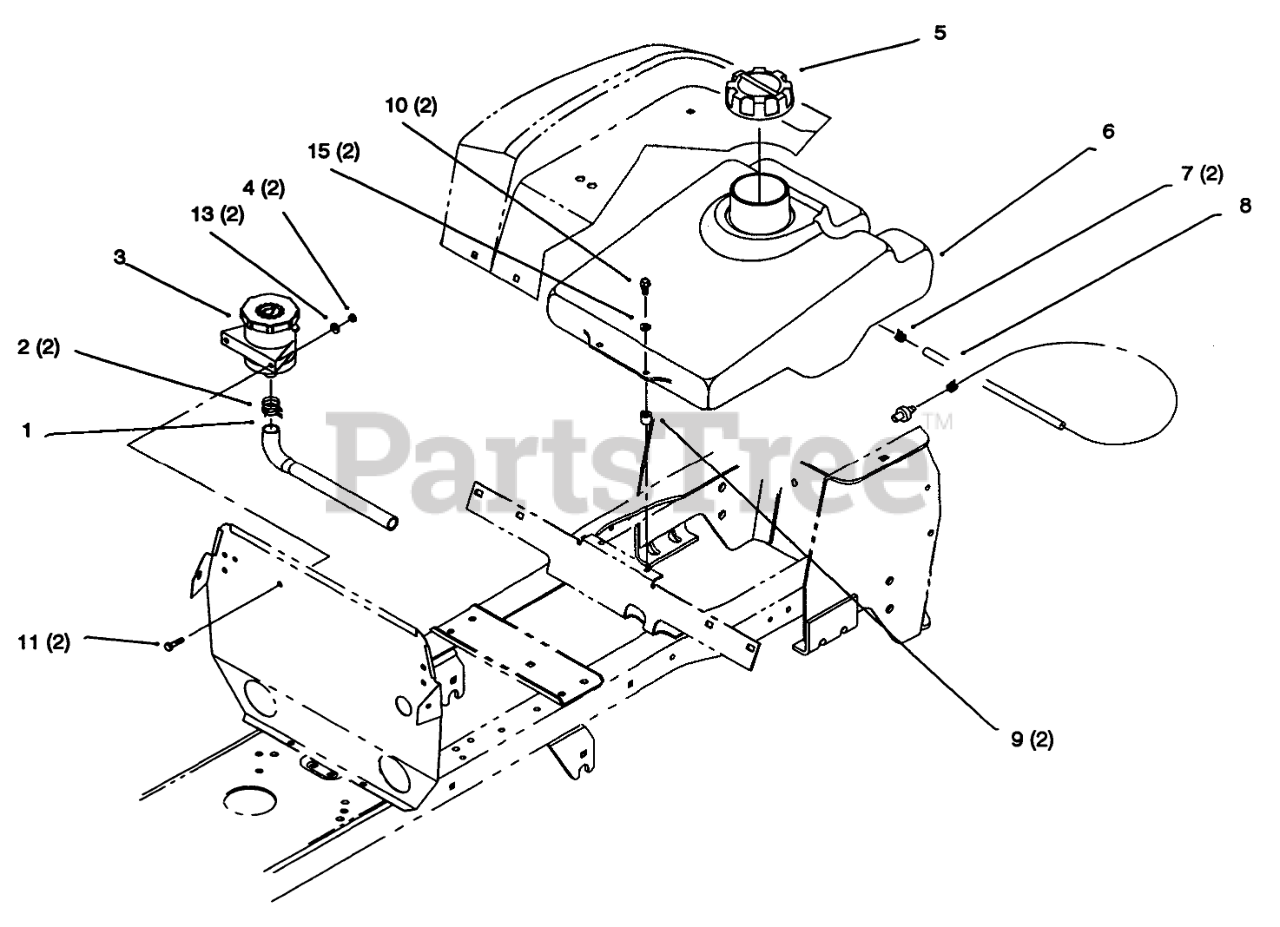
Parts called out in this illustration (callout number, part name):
1	Hose (Only On: 72043, 72103, 72063, 72083)
2	Clamp-Hose (Only On: 72043, 72103, 72063, 72083)
3	Reservoir (Only On: 72043, 72103, 72063, 72083)
4	Nut-Hex Lock (Only On: 72043, 72103, 72063, 72083)
5	GAS CAP ASM
6	Tank-Gas
7	CLAMP-HOSE
8	Hose-Fuel Line (Only On: 72043, 72042, 72063, 72062)
8	Hose-Fuel line (Only On: 72103, 72083)
9	Spacer-Fuel Tank (Only On: 72043, 72103, 72063, 72083)
10	Screw-HHST (Only On: 72043, 72103, 72063, 72083)
10	Screw-TAP (Only On: 72042, 72062)
11	Screw-HH (Only On: 72043, 72103, 72063, 72083)
13	Washer-Flat (Only On: 72043, 72103, 72063, 72083)
15	Washer-Flat (Only On: 72043, 72103, 72063, 72083)
